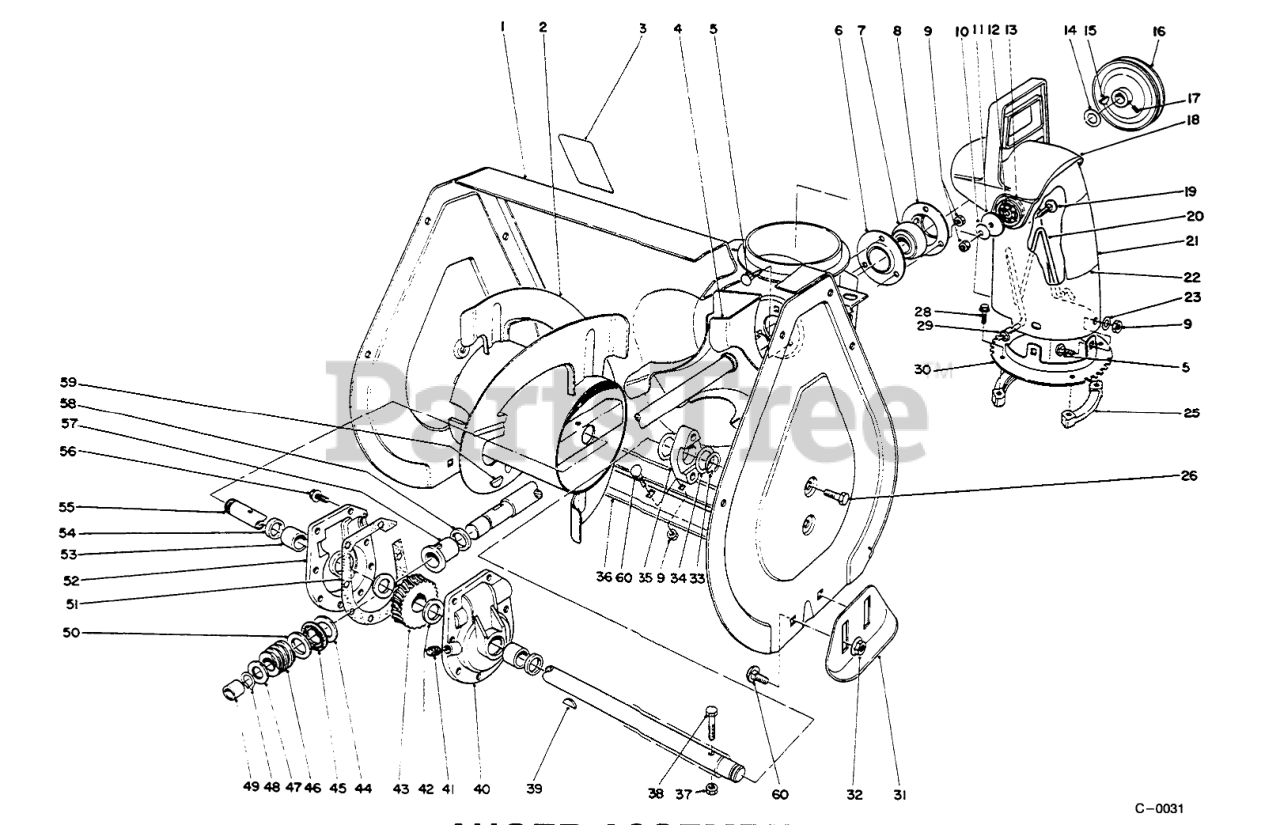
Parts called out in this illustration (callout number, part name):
1	Housing-Auger (Incl. Ref. #3)
2	Auger R.H.
3	DECAL-WARNING, AUGER
4	Shaft & Impeiler
5	SCREW-CARR
6	Flange-Bearing Front
7	BEARING-BALL
8	Flange-Bearing Rear
9	NUT-LOCK, NI
10	WASHER-BELLEVILLE
11	WASHER-FLAT
12	PLATE-FRICTION
13	WASHER-RUBBER
14	WASHER
15	KEY-WOODRUFF
16	PULLEY
17	SCREW-SET, SQH
18	CHUTE-DEFLECTOR
19	SCREW-CARR
20	WIRE-CHUTE
21	Chute-Discharge (Incl. Ref.# 22) Model 38052
22	Decal-Danger
23	WASHER-PLAIN
25	RING-CHUTE, RETAINER
26	SCREW-HWHTF
28	SCREW-SPECIAL
29	NUT-PUSH
30	Chute Ring
31	Skid
32	NUT-HF
33	RING-RETAINING
34	WASHER
35	BEARING-AUGER
36	Blade-Scraper
37	NUT-LOCK, NI
38	SCREW-HH
39	KEY-WOODRUFF
40	Gear Case L.H.(Incl. Ref. #53 & 54)
41	PLUG-PIPE, SQH
42	WASHER-THRUST
43	GEAR-WORM, 27T
44	WASHER-THRUST
45	BEARING-THRUST
47	WASHER-THRUST
48	Ring-Snap
49	BUSHING
50	WASHER-THRUST
51	GASKET-CASE, GEAR
52	Gear Case R.H .(Incl. Ref. #53 & 54)
53	BUSHING
54	SEAL-OIL
55	AUGER SHAFT
56	SCREW-TAPTITE
57	BUSHING-INPUT
58	RING-QUAD
59	KEY-WOODRUFF
60	BOLT-CARR
